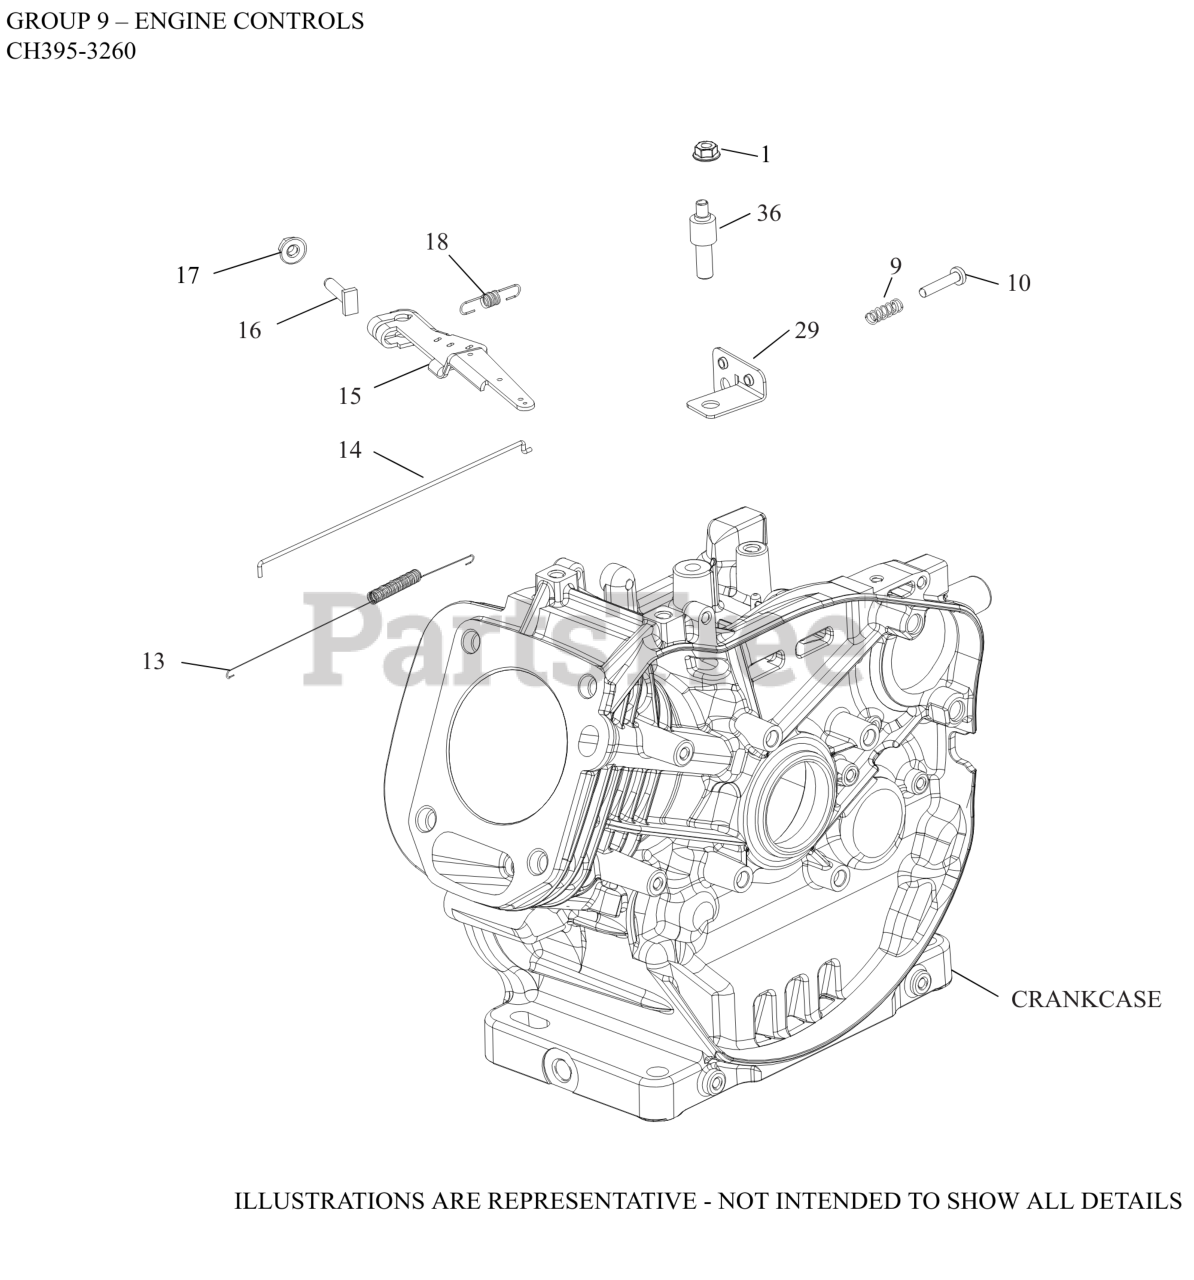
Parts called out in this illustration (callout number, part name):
1	NUT, HEX FLANGE LOCK (M6)
9	SPRING, COMPRESSION
10	SCREW, SPEED ADJUSTING
13	SPRING, LINKAGE
14	LINKAGE, GOVERNOR
15	KIT, GOVERNOR LEVER
16	SCREW, RECTANGLE HEAD (M6)
17	NUT, HEX FLANGE (M6) - USE 14 100 16-S
18	SPRING, GOVERNOR
29	BRACKET, CONTROL
36	STUD, CONTROL LEVER
